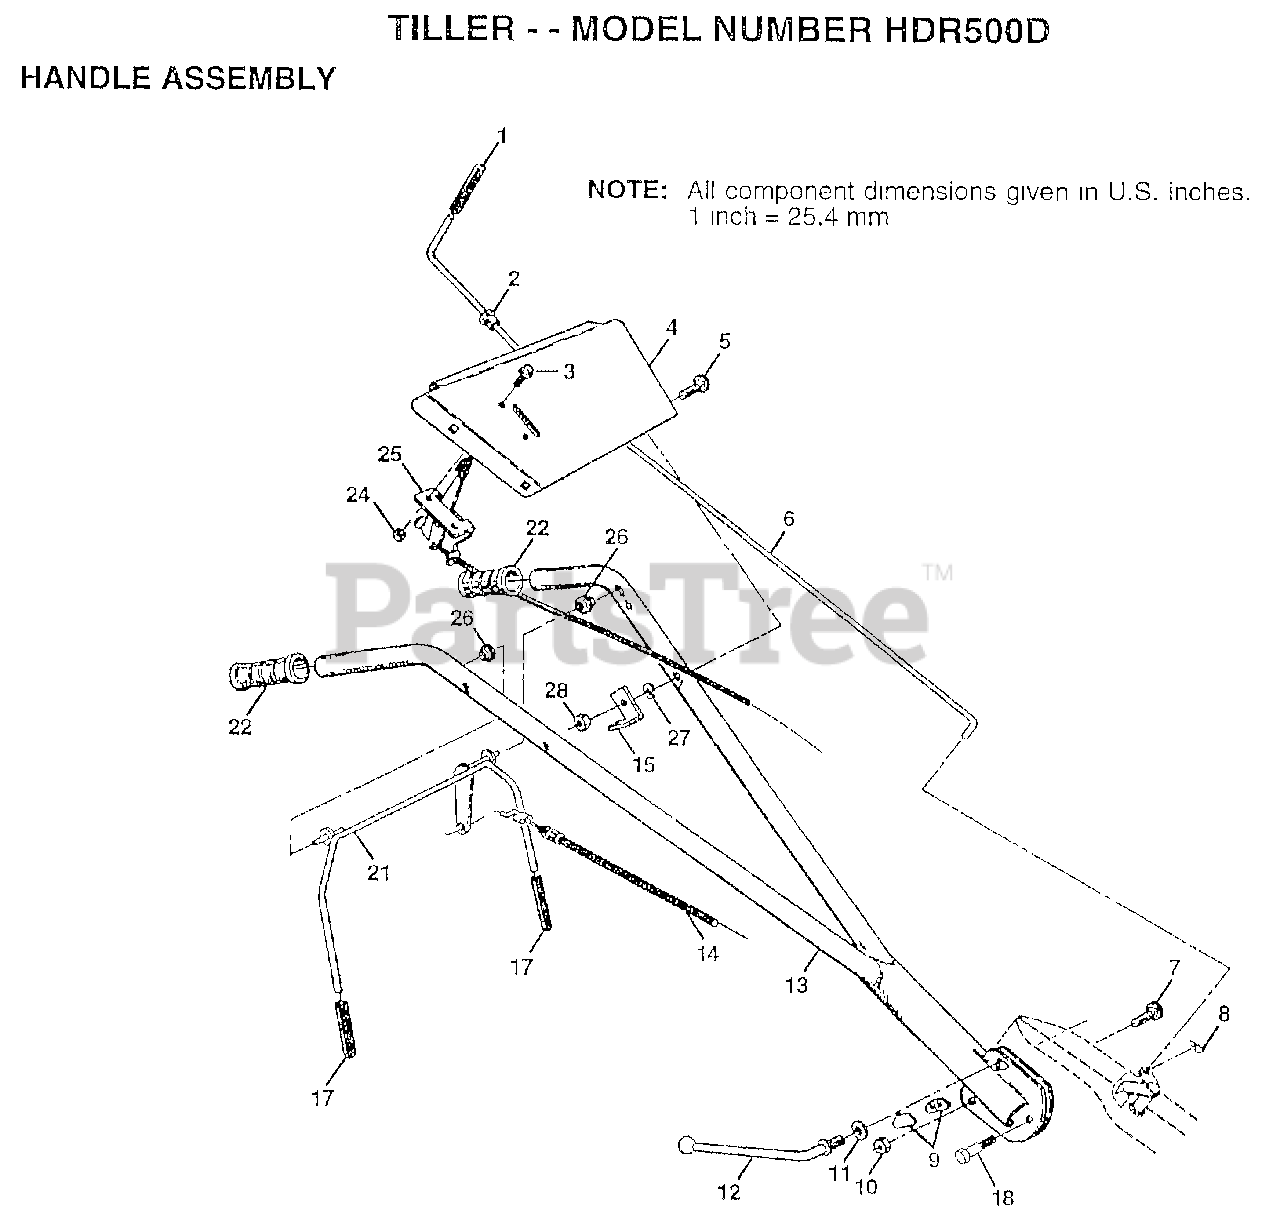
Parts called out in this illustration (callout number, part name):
1	GRIP TI
2	BUSHING
3	SCREW.PNHD.10-24
4	BRACKET.HDLE.TILL
5	BOLT CARRIAGE CRT
6	ROD SHIFT CRT
7	BOLT D
8	RETAINER M
9	LOCK CRT
10	LOCKNUT
11	WASHER CRT
12	LEVER LOCK CRT
14	CABLE.CLUTCH.Z-BE
15	BRACKET.CLUTCH.CA
17	GRIP BAR CRT
18	BOLT PIVOT
21	BAR.ASM.CNTRL.VPL
22	"GRIP,HANDLE"
25	"CONT,THROTTLE"
26	GROMMET.HANDLE.V-
27	LOCKWASHER
28	NUT
